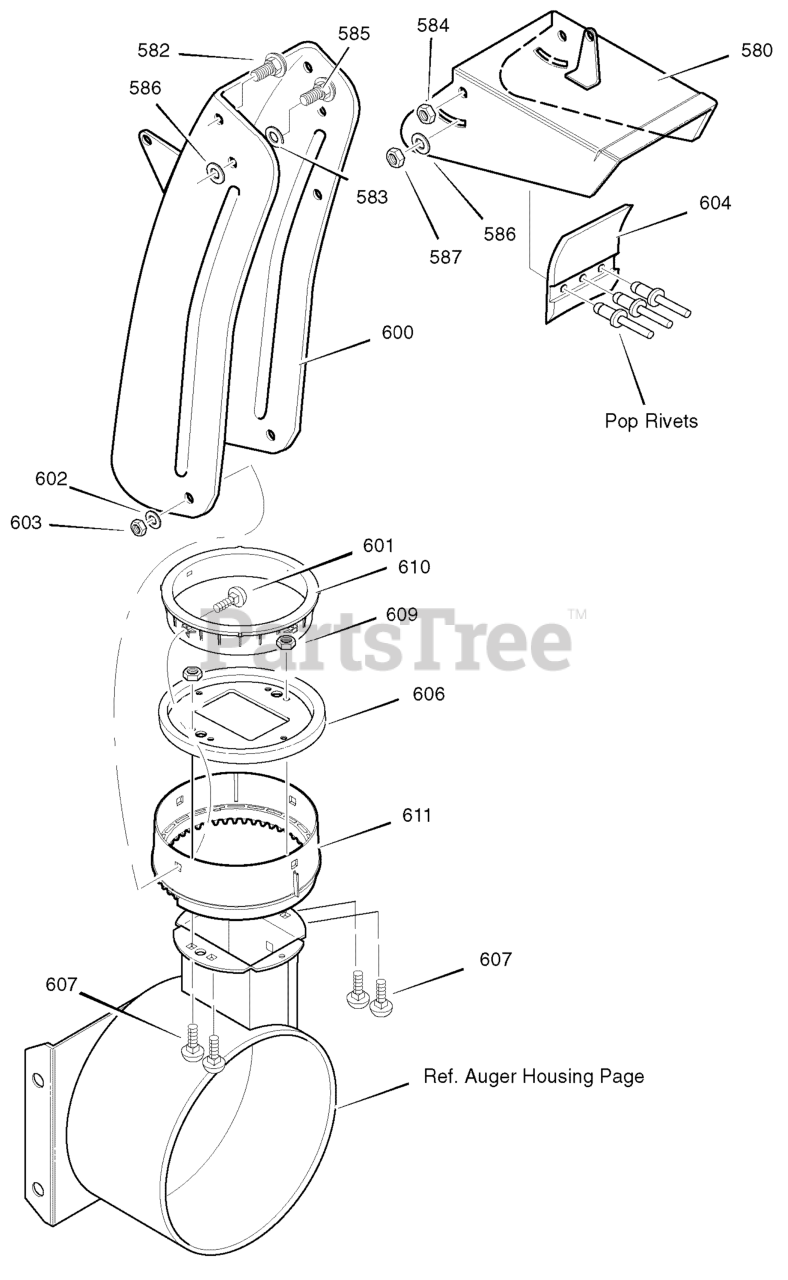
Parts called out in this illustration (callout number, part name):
580	CHUTE, UPPER W/REMOTE
582	SCREW, 5/16-18 x 0.75
583	WASHER, PLASTIC
585	SCREW, 5/16-18 x 0.75
586	WASHER, PLASTIC
600	CHUTE, LOWER W/REMOTE
601	CARRIAGE BOLT, 5/16-18 x 1
602	WASHER, FLAT
606	CHUTE COLLAR
610	RETAINER, RING INNER
611	RETAINER, RING OUTER
